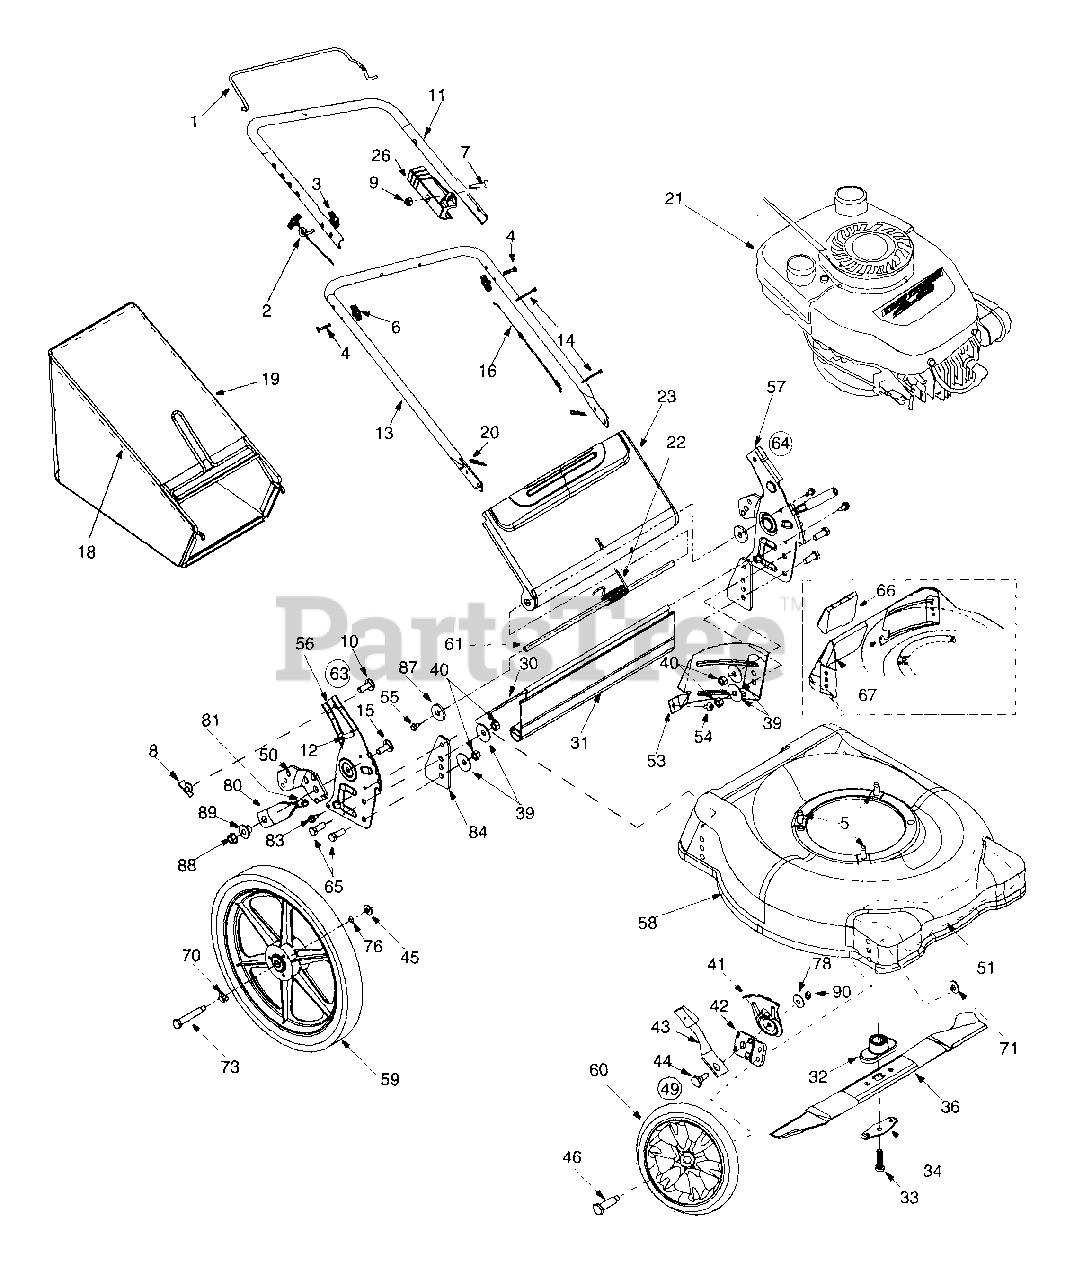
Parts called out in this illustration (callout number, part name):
2	Rope Guide
3	Handle Knob
4	Curved Hd. Bolt 5/16-18 X 2" Lg.
5	Scr. TT. 3/8-16 X 1.00" Lg. Hx Indwash.
6	Hand Knob
7	Oval C-sunk Scr. 1/4-20 X 1.310 Lg.
8	Wing Nut
9	Hex Lock Nut 1/4-20 Thd.
10	Carriage Bolt 1/4-20 x 0.75"
11	Upper Handle
13	Lower Handle
14	Cable Tie
15	Weld Screw 3/8-16 x 1.0"
16	Control Cable - 51"
19	Grass Catcher Bag
20	Hairpin Clip
21	Engine, Tecumseh
22	Door Spring
30	Wire Rod
31	Rear Flap
32	Blade Adapter
33	Hex Bolt 3/8-24 X1.5 Lg.
34	Blade Bell Support
36	19" Blade (Mulching)
39	Bell Washer.39 I.d. X1.38 I.d.
40	Hex Nut 3/8-16 Thd.
41	Height Adj. Plate
43	Spring Lever, Front Wheel
44	Shoulder Bolt, .5" Dia. X .357"
45	Bell Wash. .38" I.d. X .88" O.d.
46	Front Axle Bolt
49	Height Adjuster Ass'y Comp. - R.H.
50	Pivot Bar - R.H.
55	Scr. TT. 1/4-20 x .500 HxIndWash.
60	Fr. Wheel Ass'y. 8 x 1.7 Aero Grey
61	Chute Door Pivot Rod
66	Rear Mulch Plug
70	Wave Washer
71	Spring Washer
73	Rear Axle Bolt
76	Spacer
78	Bell Washer
80	Spring Lever, Rear
81	Foam Grip
83	Scr. AB 1/4-14 x .625 HxIndWash.
84	Handle Bracket Support Plate
87	Flat Washer 3/8 x 1.25
88	Flange Lock Nut
89	Shoulder Spacer 3/8"
90	Hex Nut 3/8-16 Thd.
